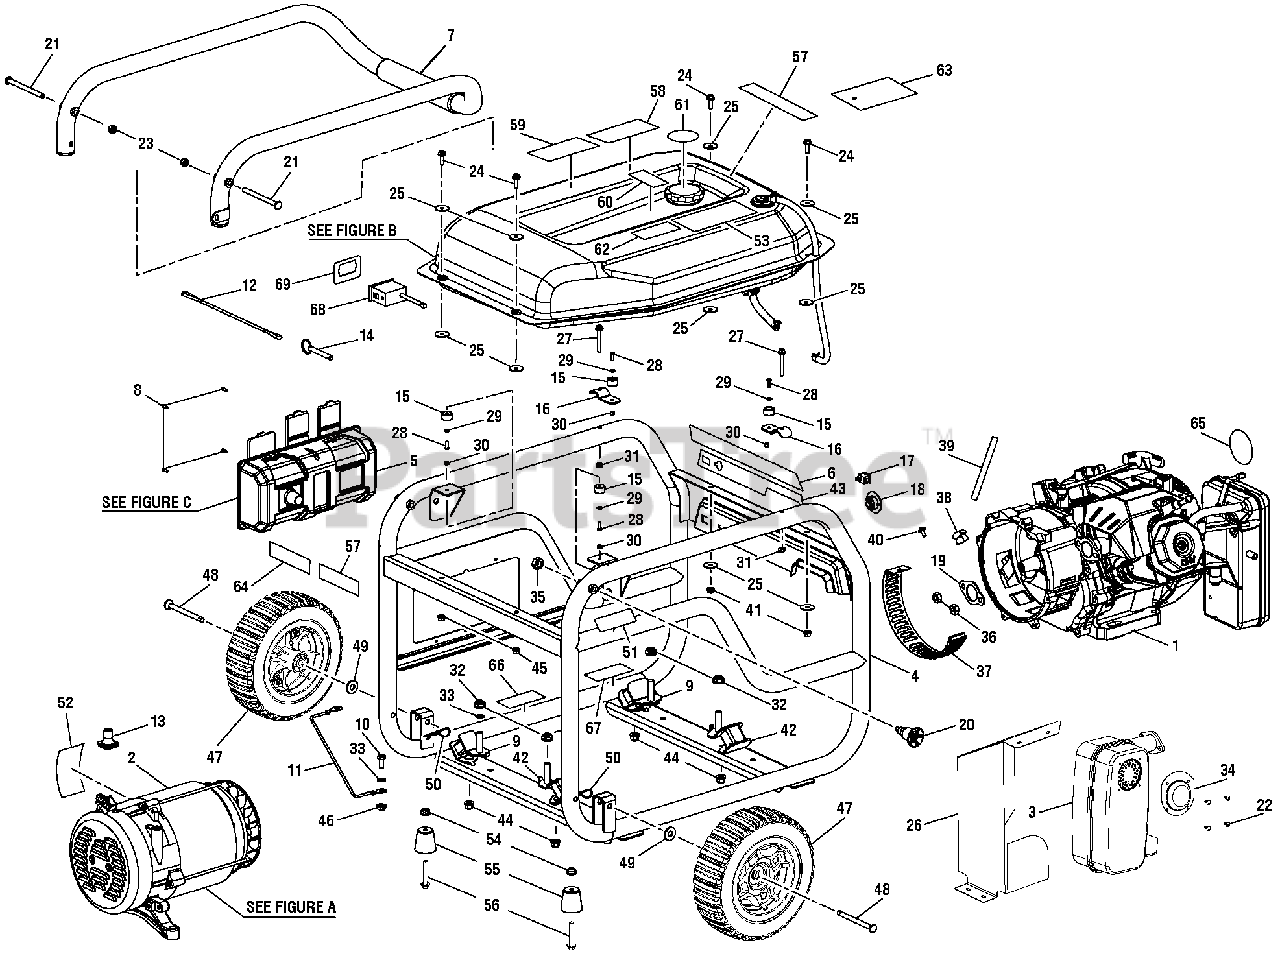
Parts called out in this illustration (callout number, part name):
1	Engine (Rato 390cc)
2	Generator Head Assembly (See Fig. A)
4	Frame Assembly
5	Control Panel Assembly (See Fig. C)
6	Logo Label
7	Handle Assembly
8	Screw (6-20 x 3/8 in.)
9	Engine Isolator (Right)
10	Bolt (5/16-18 x 3/4 in.)
11	Ground Wire Assembly
13	Rubber Sleeve
14	Release Pin
15	Handle Bumper
16	Handle Support Bracket
17	On/Off Switch
18	Fuel Valve Bezel
19	Muffler Gasket
20	Handle Release Pin
21	Pivot Pin (Handle)
22	Screw (8-32 x 3/8 in.)
23	Lock Nut (5/16-18)
24	Bolt (M6 x 20 mm, Hex Washer Hd.)
25	Washer (M6)
26	Heat Shield
27	Bolt (M6 x 45 mm)
28	Bolt (M4 x 12.5 mm, Hex Hd.)
29	Washer (M4)
30	Lock Nut (M4)
31	Lock Nut (M6)
32	Lock Nut (5/16-18)
33	Star Washer (5/16 in.)
34	Spark Arrestor
35	Lock Nut (1/2-20)
36	Hex Nut (M8)
37	Fan Cover (Generator Head)
38	Plug (Generator Head)
39	Heat Shrink Tube
40	Screw (M5 x 10 mm, Hex Hd.)
41	Flange Nut (M6)
42	Engine Isolator (Left)
43	Start Label
44	Lock Nut (M8)
45	Hex Nut (1/4-20)
46	Hex Nut (5/16-18)
48	Axle Bolt
49	Washer (M10)
50	Hitch Pin
51	Hot Surface Label
52	Data Label
53	Danger Label
54	Lock Nut (M8)
55	Foot Assembly
56	Bolt (M8 x 1-1/4)
57	Fire Distance Label (Eng/Sp)
58	CPSC Label
59	Fire Danger Label
60	E85 Label
61	Fuel Stabilizer Label
62	Combustion Label (Eng/Sp)
63	Warning Hangtag
64	Ground Warning Label
65	Recoil Housing Label
66	Lubricant Label
67	Inquires label
68	Analog Hour Meter
69	Systems Monitor Label
